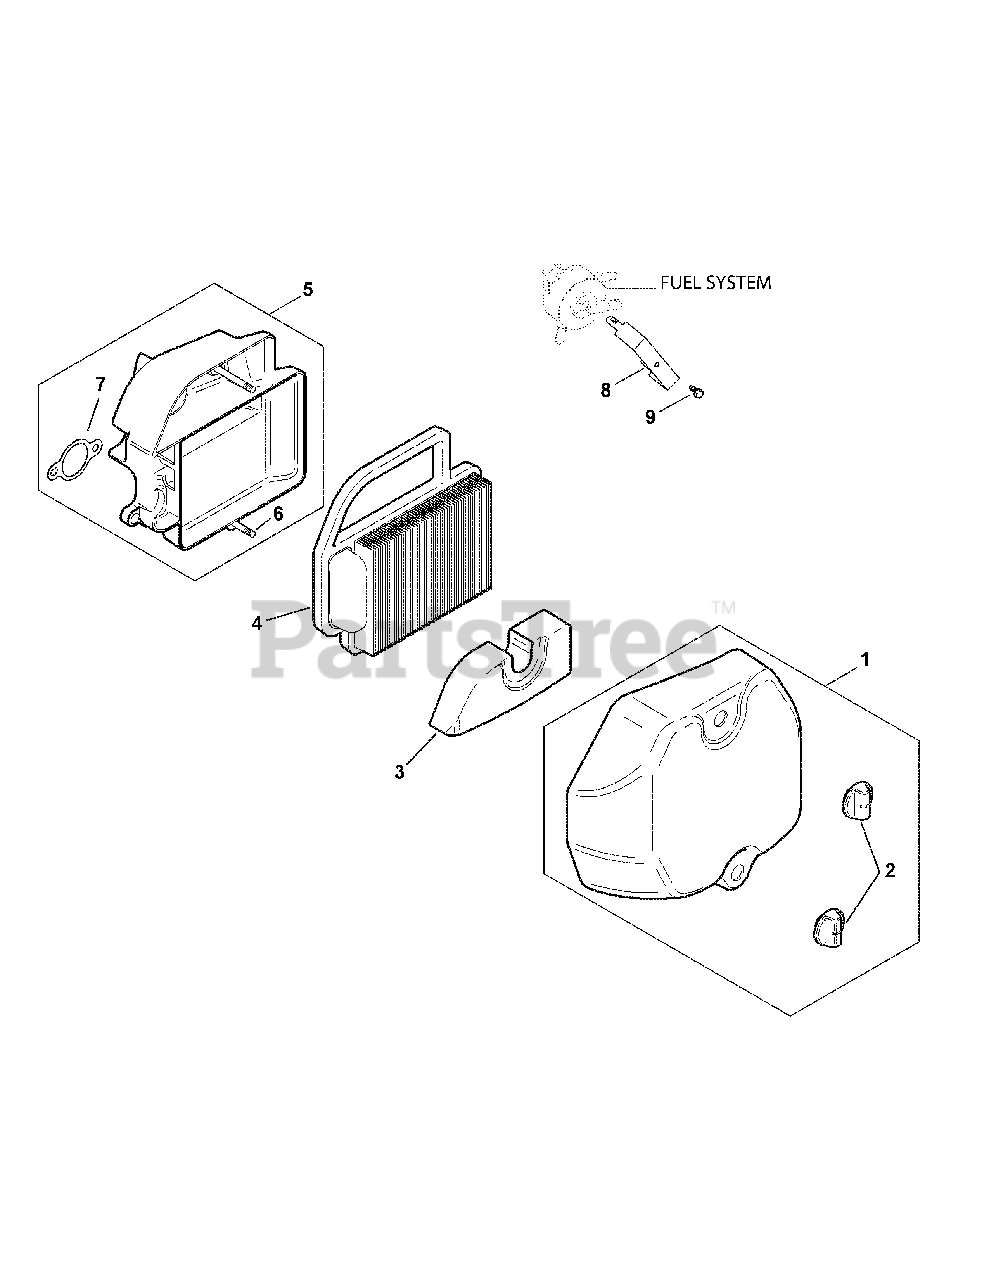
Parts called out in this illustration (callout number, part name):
1	Air Cleaner Cover Kit
3	Pre-Cleaner Element (Dry)
4	Air Cleaner Element
5	Air Cleaner Base Kit
6	Air Cleaner Base Stud
7	Air Cleaner Base Gasket
8	Fuse Block
9	Fuse Block
